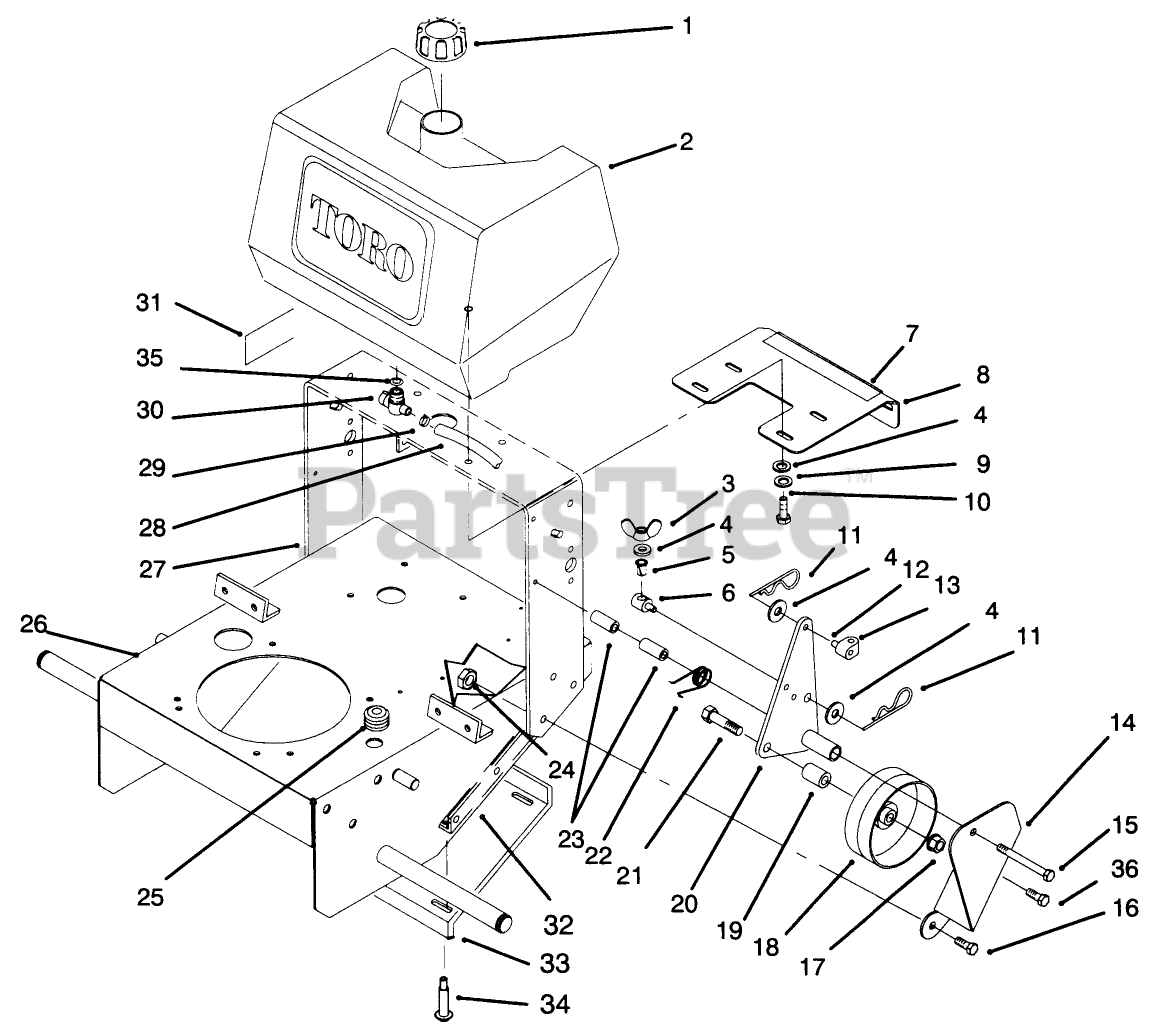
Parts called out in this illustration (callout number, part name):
1	GAS CAP ASM
2	FUEL TANK
3	NUT-WING
4	WASHER-PLAIN
5	BUSHING-NYLON
6	FITTING-ROD
7	DECAL - GROUND SPEED
8	Plate
9	WASHER-LOCK
10	SCREW-HH
11	PIN-COTTER
12	PIN-CLEVIS
13	FITTING-ROD
14	Bracket-LH
15	SCREW-HH
16	SCREW-HH
17	NUT-LOCK, NI
18	IdlerWheel
19	WHEEL IDLER SPACER
20	BRACKET-Idler, LH
21	SCREW-LEVELER
22	SPRING-TORSION, LH
23	SPACER-PIVOT, IDLER
24	NUT-LOCK, NI
25	GROMMET
26	Frame
27	Frame Rear
28	HOSE-FUEL
29	CLAMP-HOSE
30	VALVE-FUEL
31	DECAL-SHUT OFF, FUEL
32	Mount-Angle
33	Panel-Bottom
34	SCREW
35	O-RING
36	SCREW-HH
